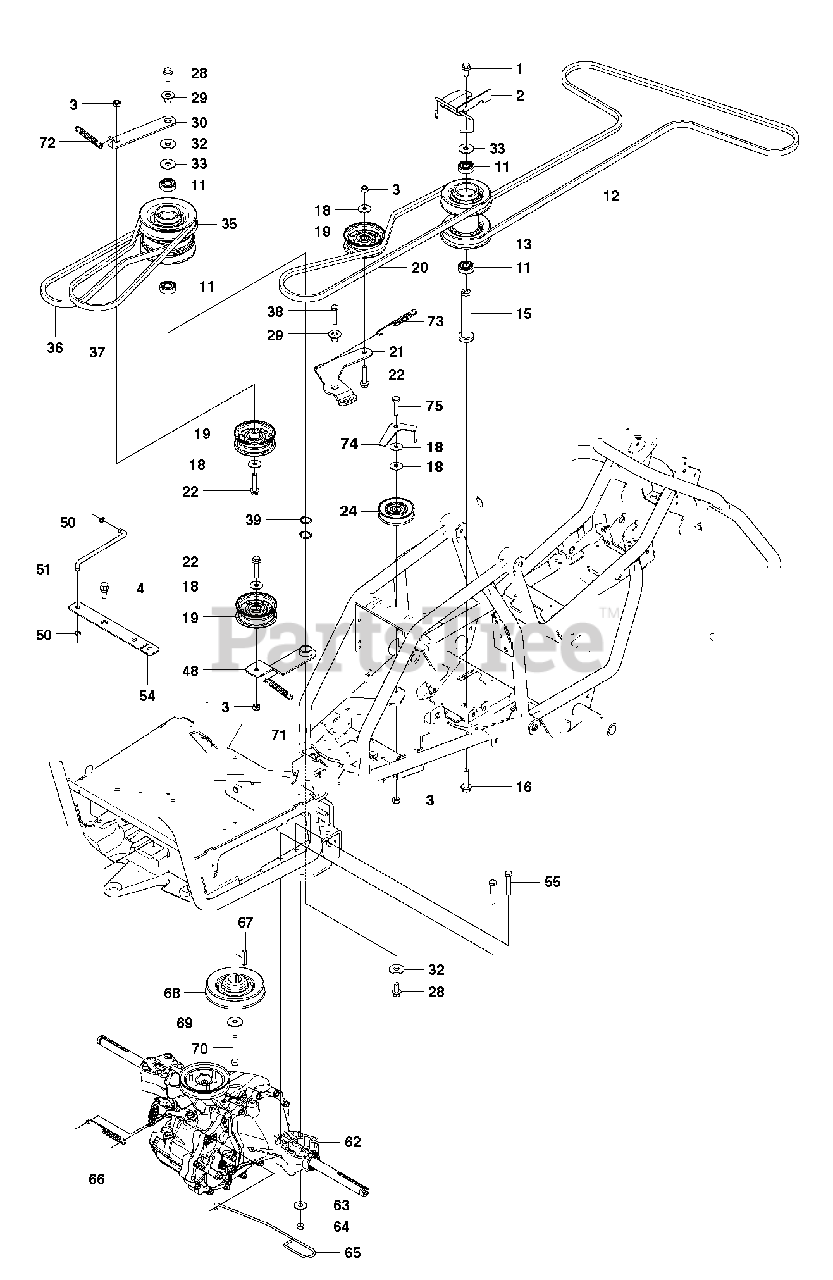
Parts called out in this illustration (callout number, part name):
3	LOCKNUT M8
11	BALL BEARING 6004-2RS1
12	BELT
19	IDLER PULLEY
38	BOLT
39	RETAINING RING SGA 20
63	WASHER BRB 8.4X17
64	NUT
66	SPRING
